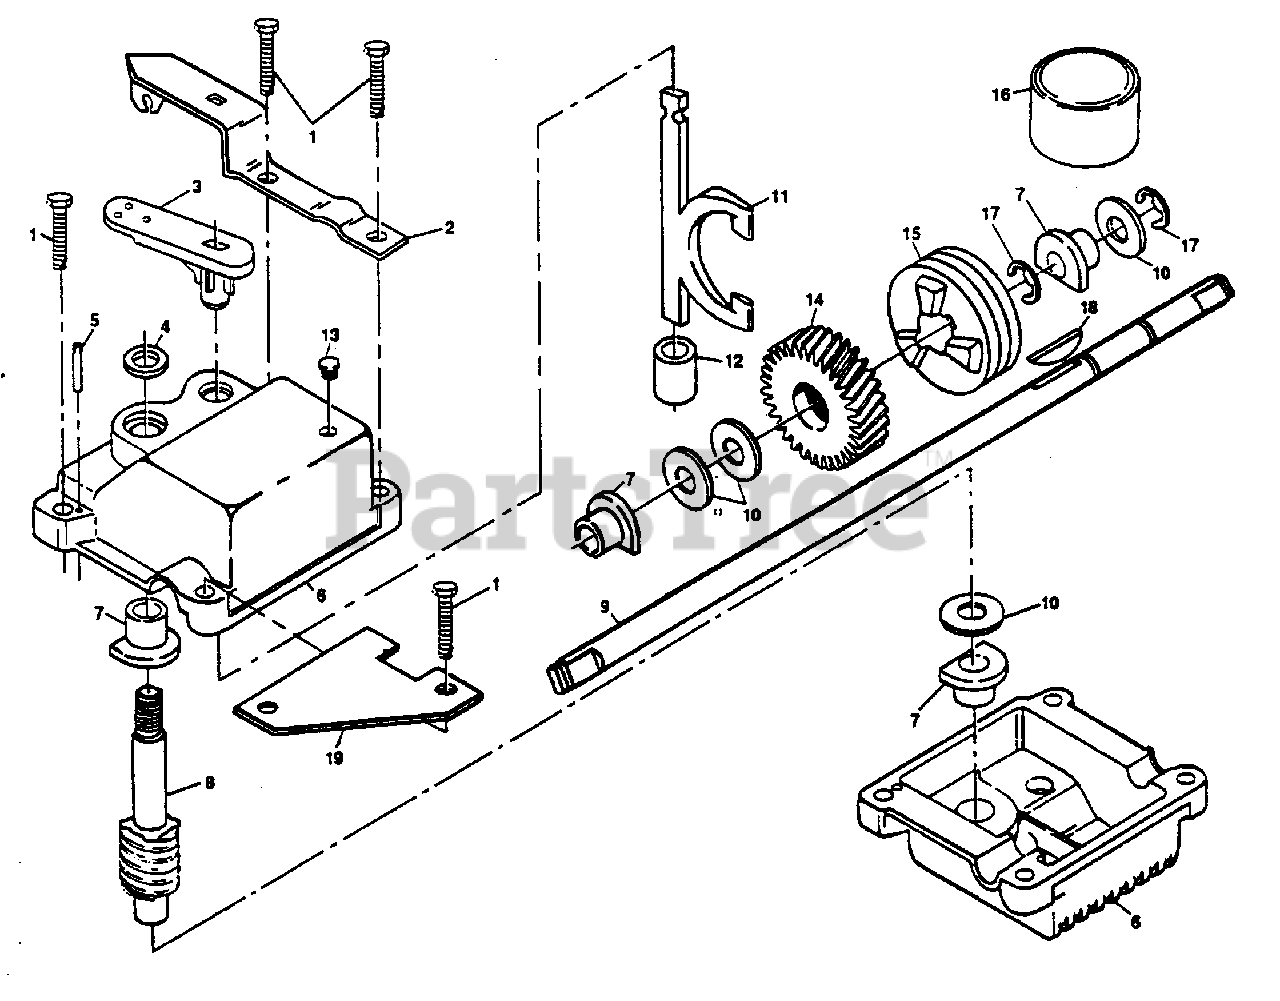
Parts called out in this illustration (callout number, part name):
1	Screw, Tapping 1/4-20 x 1-1/4 (AYP part number)
2	Bracket, Adjusting (AYP part number)
3	Shifter (AYP part number)
5	Pin, Groved 1/8 x 1/2 (AYP part number)
6	Gear Case Halves, Upper and Lower (Includes Key #4, 5 and 7) (AYP part number)
8	Shaft, Worm (AYP part number)
9	Drive Shaft (AYP part number)
10	Washer, Hardened (AYP part number)
11	Yoke, Clutch (AYP part number)
12	Bushing (AYP part number)
13	Plug (AYP part number)
14	Gear, Helical (AYP part number)
15	Jaw, Clutch (AYP part number)
16	Grease (AYP part number)
18	Key, Hi-Pro (AYP part number)
19	Spring Bracket (AYP part number)
